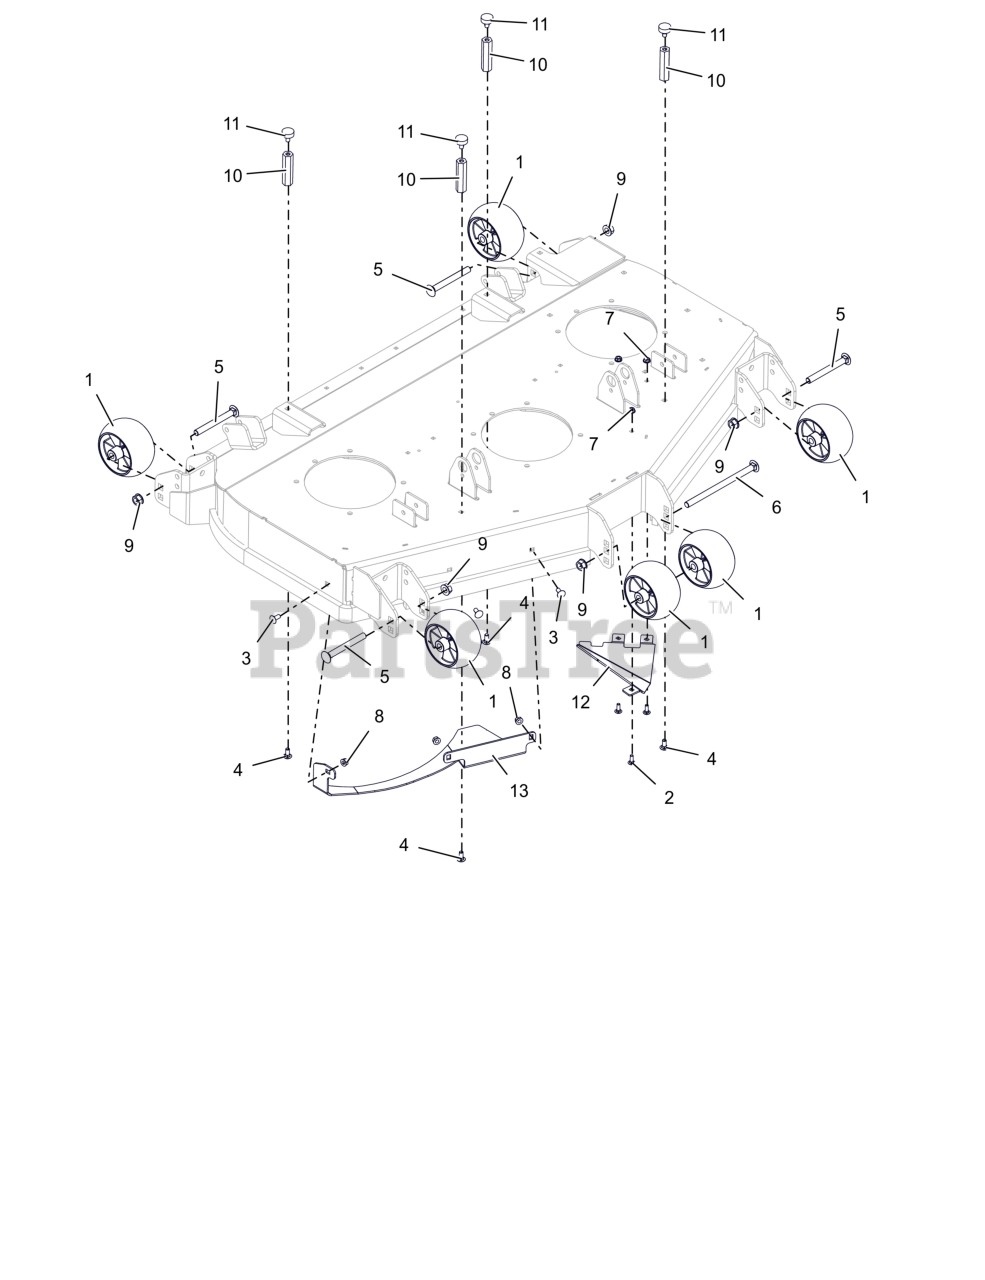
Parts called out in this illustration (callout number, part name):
1	WHEEL, ANTI SCALP - 5X3 CTR W/RIBS
2	BLT, RHSN .25-20X.750 G5 ZCC
3	BLT, RHSSN.31-18X.750 G5 ZCC
4	BLT, RHSN .31-18X.75 G5 ZCC LT
5	BOLT, RHNS .50-13X4.50 G5 ZCC NS
6	BOLT, RHNS .50-13X8.00 G5 ZCC NS
7	NUT-LK-CTR-FLG .25-20 ZC120
8	NUT,LK-CTR-FLG .31-18 GF ZCC
9	NUT-LK-CTR-FLG .500-13 GG ZCC
10	NUT, COUPLING .31-18 X 3.00
11	BUMPER, RUBBER
12	BAFFLE, 48" TRIANGLULAR INSERT (ORANGE)
13	DEFLECTOR, BAFFLE BOLT-IN (ORANGE)
